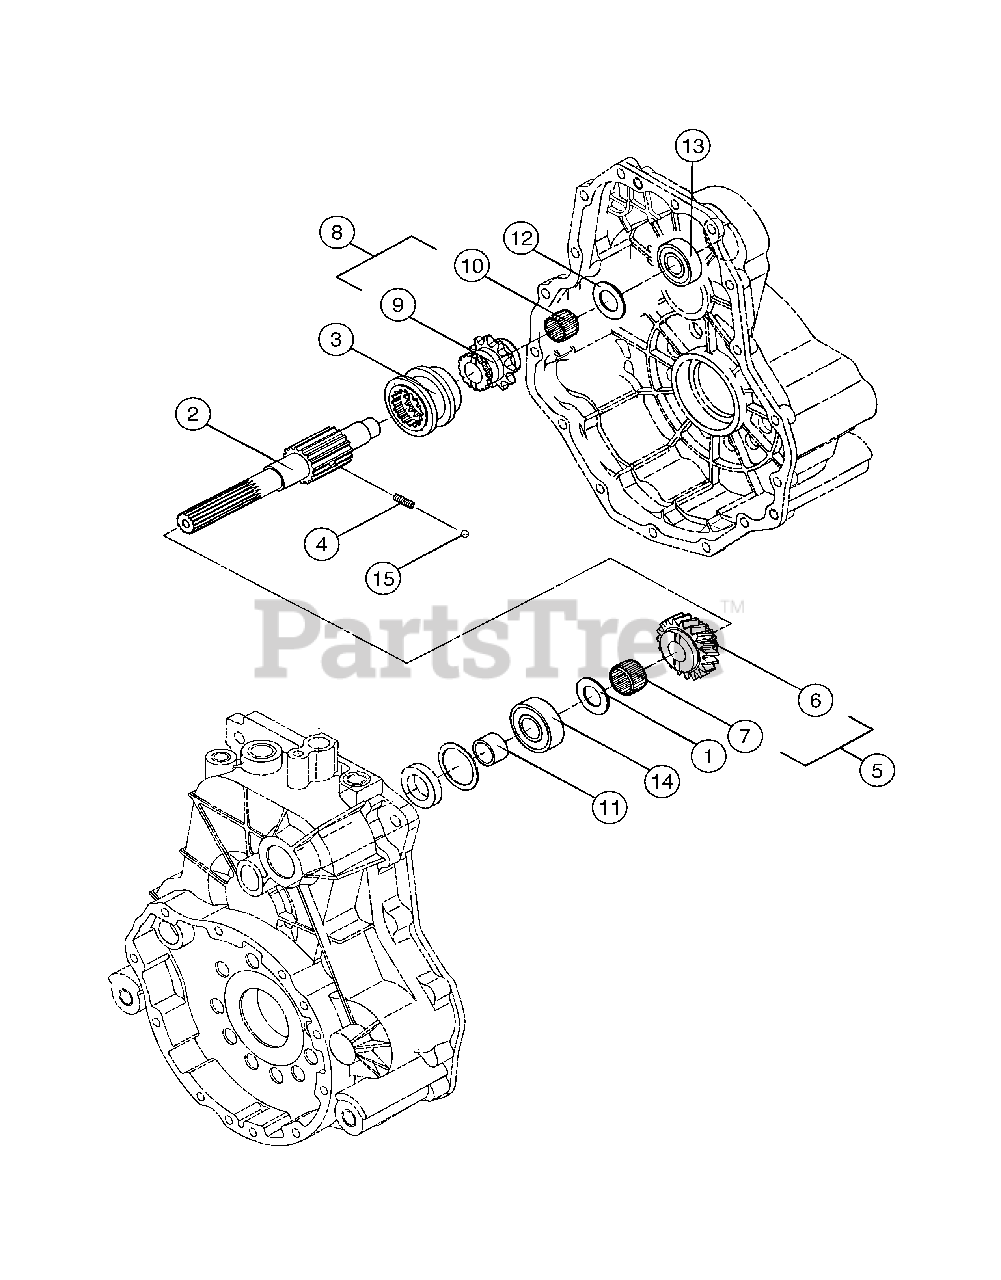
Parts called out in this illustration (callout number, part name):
3	Shifter
4	Spring 29.5
4	Spring 18
5	Gear Asm
8	Sprocket Asm
15	Bearing Ball, 1/4
